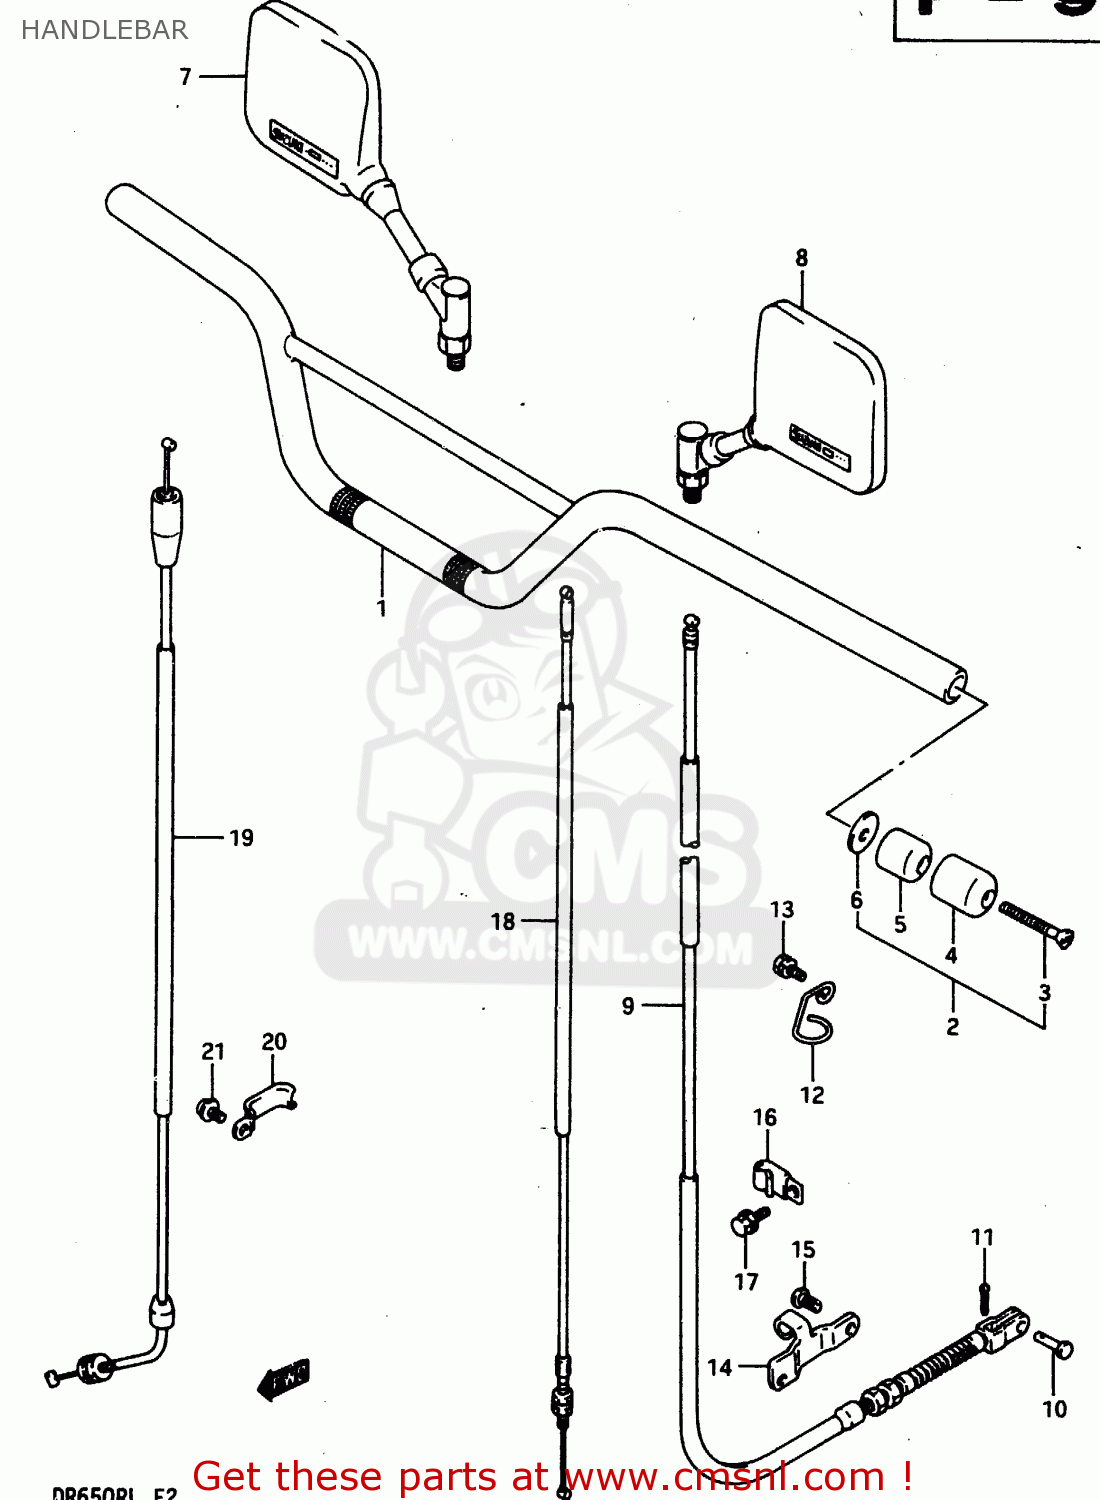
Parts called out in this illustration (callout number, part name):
1	HANDLEBAR(BLACK)
2	BALANCER SET,HANDLEBAR
3	SCREW
4	CAP,BALANCER
5	BALANCER,HANDLEBAR
6	SPACER,BALANCER
7	MIRROR ASSEMBLY,REAR VIEW
8	MIRROR ASSEMBLY,REAR VIEW
9	CABLE ASSY,CLUTCH
10	PIN(L:13)
11	PIN
12	GUIDE
13	BOLT ,6X12
14	STOPPER,CLUTCH CABLE
15	SCREW
16	CLAMP
17	BOLT
18	CABLE ASSY,DECOMP
19	CABLE ASSY,THROTTLE
20	CLAMP
21	SCREW
